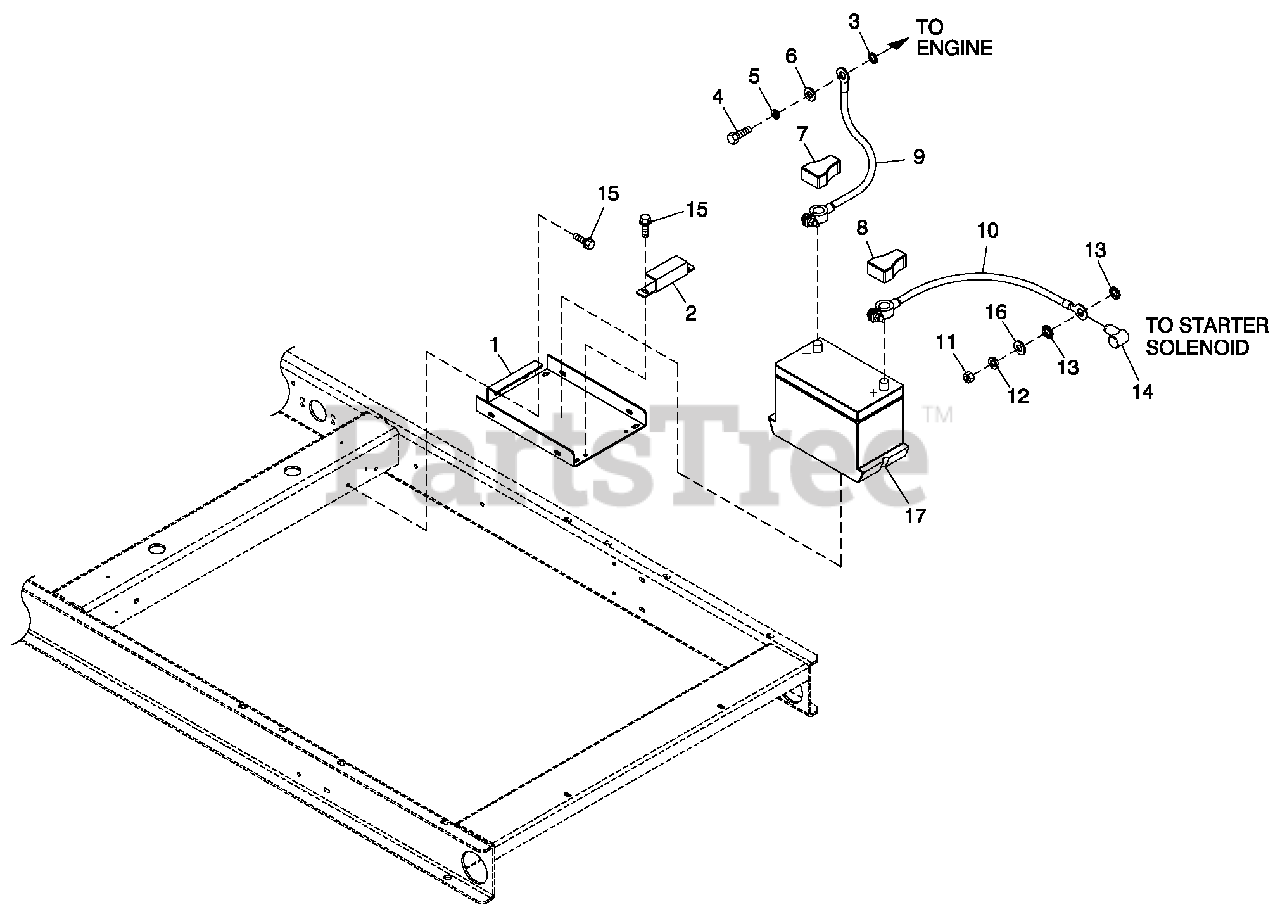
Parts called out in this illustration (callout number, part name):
1	ROTOR-2390-45KD1 CPL
2	ROTOR-2390-35KD1 CPL
3	ROTOR-2390-45KD1 CPL (G2)
4	ROTOR-2390-35KD1 CPL (G2)
5	ROTOR 25KW 3PH DIRECT 390 1800
6	ROTOR 25KW 1PH DIRECT 390 1800
7	BATTERY POST COVER RED +
8	BATTERY POST COVER BLACK -
9	CABLE BATTERY BLACK #1 X 18.00
10	STATOR-390 45K 2P 1PH DIRECT
11	STATOR-2390-35AD1 CPL
12	STATOR-2390-35KD1 CPL
14	STATOR-2390-35GD1 CPL
15	STATOR-2309-45KW 2P 3PH 208V
16	STATOR-2309-45-KD1 CPL
17	BATTERY 12VDC 75-AH 26
